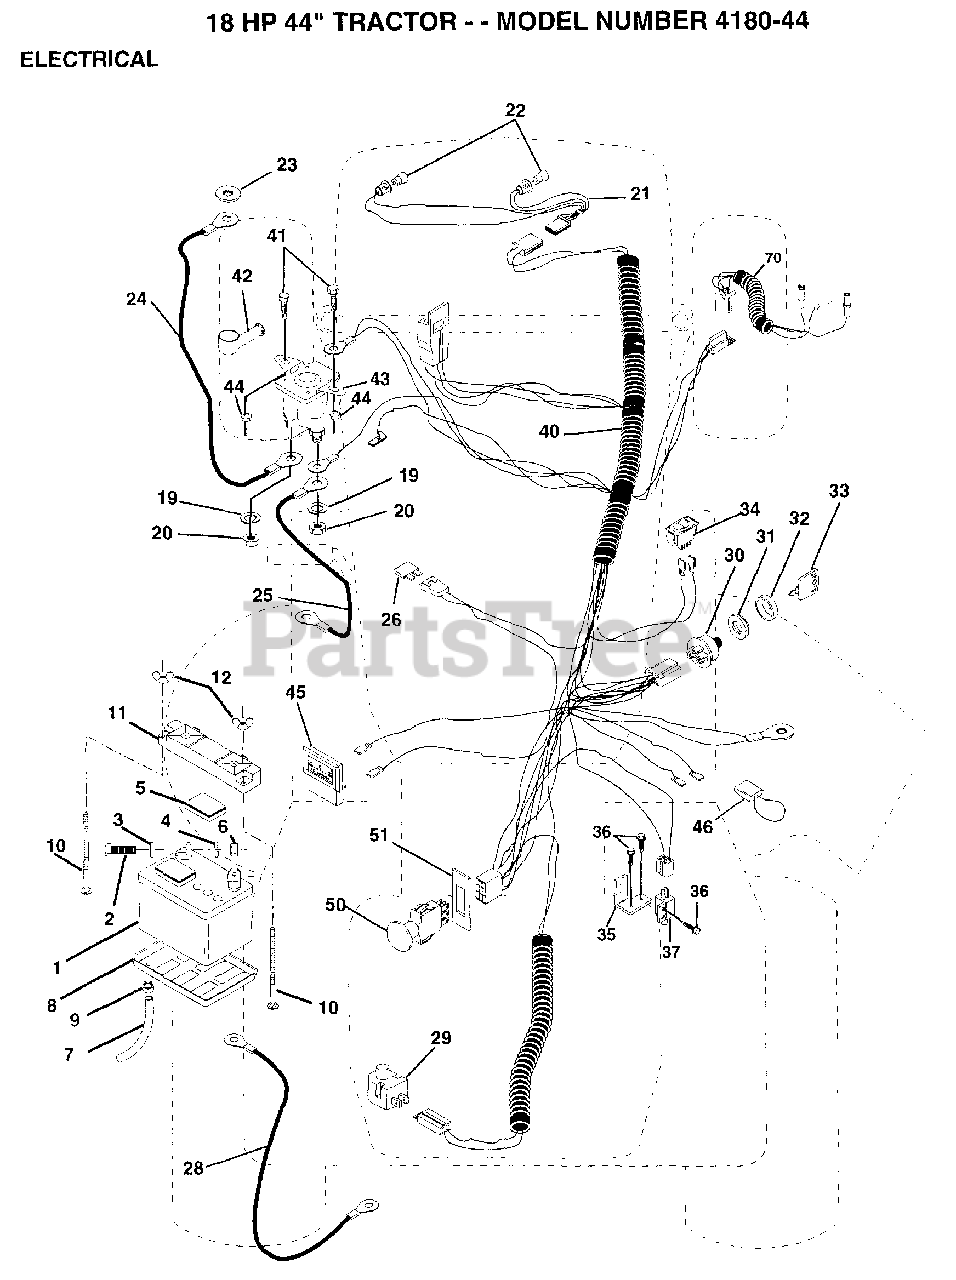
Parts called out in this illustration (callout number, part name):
2	BOLT LT
3	WASHER
4	LOCKWASHER
5	"CAP,BATTERY "
7	"DRAIN TU T, BATT"
8	"TRAY T, BATTERY"
9	HOSE CLAMP T
10	BOLT
20	NUT
21	"HARNESS,LIGHT SOC"
22	HEADLAMP BULB
23	LOCKWASHER
24	"CABLE T, BATTERY"
25	CABLE-BATTERY T
26	FUSE HYT
28	CABLE T
29	SWITCH SEAT
32	COVER KEY SWITCH
33	KEY MLD GEN DELTA
34	SWITCH LT
35	BRACKET LT
36	SCREW
37	SWITCH-INTER. GT
40	HARNESS IGNITION
41	BOLT HXHD FIN
45	AMMETER
46	PROTECTION LOOP
51	RING RETAIN PTO
70	HARNESS ENG B&S
